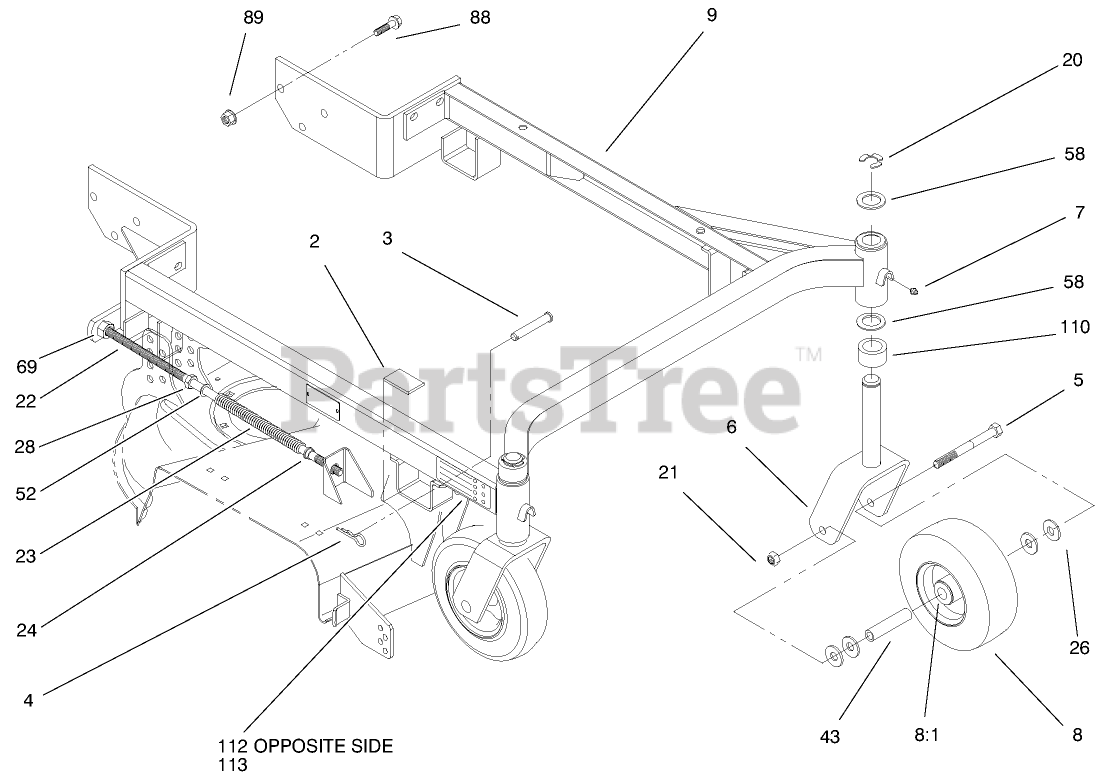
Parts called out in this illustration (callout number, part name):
2	CUSHION-RUBBER
3	PIN-CLEVIS
4	PIN-HAIR
5	SCREW-HH
6	Castor Fork
7	FITTING-GREASE
8	CASTOR WHEEL ASM
8:1	BEARING-OUTSIDE
9	CARRIER FRAME ASM
20	RING-RETAINING
21	NUT-HEX
22	SHAFT-ADJUSTING
23	SPRING
24	BUSHING-FLANGE
26	WASHER-FLAT
28	NUT-JAM
43	SPANNER-TIRE
52	WASHER
58	WASHER-THRUST
69	NUT-LOCK, NI
88	SCREW-HHF
89	NUT-HF
110	SPACER-CASTOR
112	DECAL-HOC, LH
113	DECAL-HOC, RH
